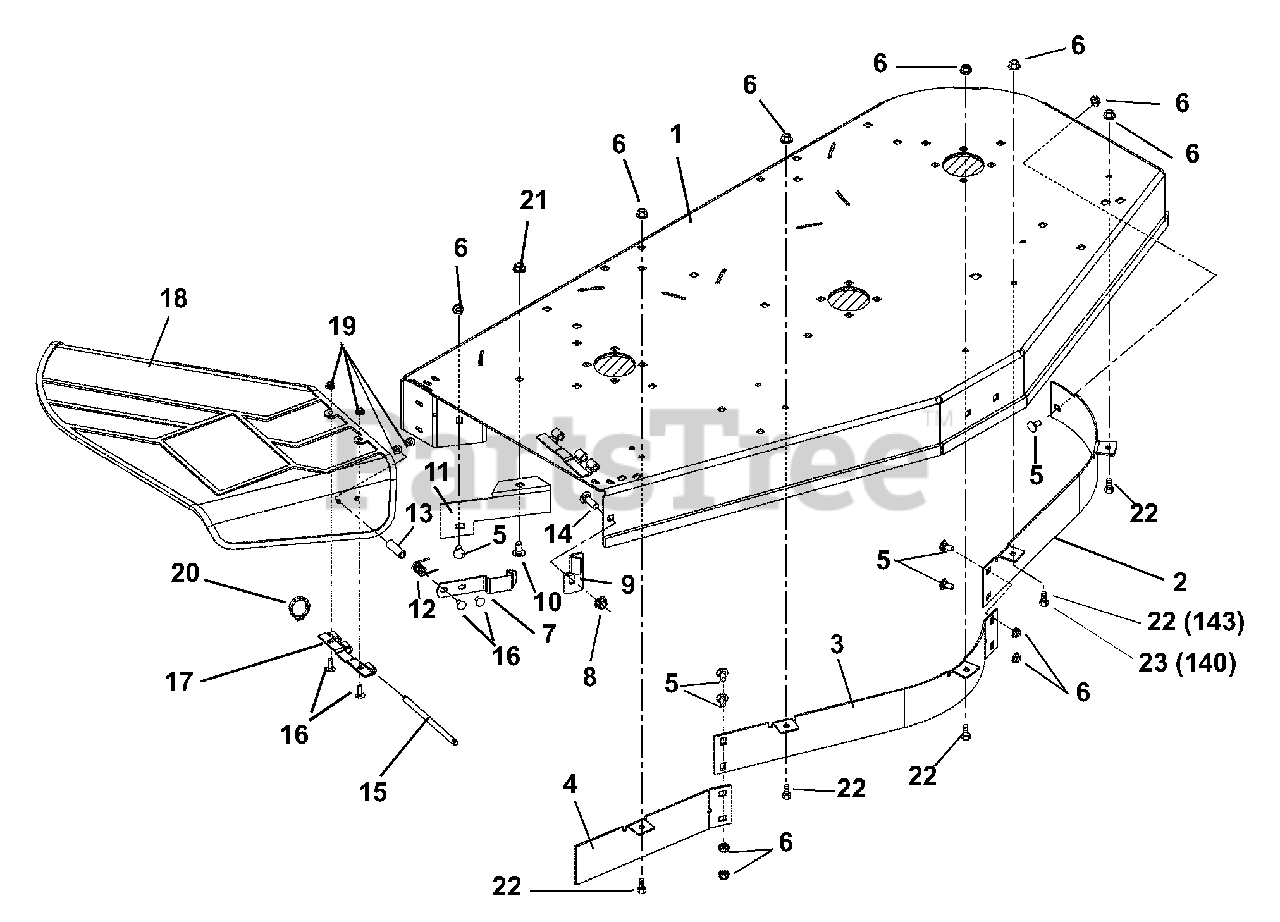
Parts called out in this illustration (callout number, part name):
1	Weldment, Deck 48"
1	Weldment, Deck 44"
2	Baffle, Left Front 48"
2	Baffle, Left Front 44"
3	Baffle, Center Front 48"
3	Baffle, Center Front 44"
4	Baffle, Right Front 48"
4	Baffle, Right Front 44"
5	Bolt-Round Head Square Neck .31-18 x .62 Grade 5
6	Nut, .312-18 Flange Nyloc
7	Flat Spring
8	Nut, Nylon Lock .38-16
9	Bracket, Chute Lock
10	Bolt-Round Head Square Neck .38-16 x .75
11	Deflector, 44"/48"
12	Spring, Torsion .095 x .50 x 1.00
13	Bushing, Sleeve .334 x .502 x 1.437
14	Bolt-Round Head Square Neck .38-16 x 1.25 Grade 5
16	Bolt-Round Head Square Neck .25-20 x .75 Grade 5
17	Hinge Plate
18	Deflector, Chute 42"
19	Nut, Nyloc Flange .25-20
20	Ring, Retaining Exterior
21	Nut, .38-16 Flange Nyloc
22	Bolt, Hex .31-18 x .75 Grade 5
23	Bolt, Hex .31-18 x 1.00 Grade 5
